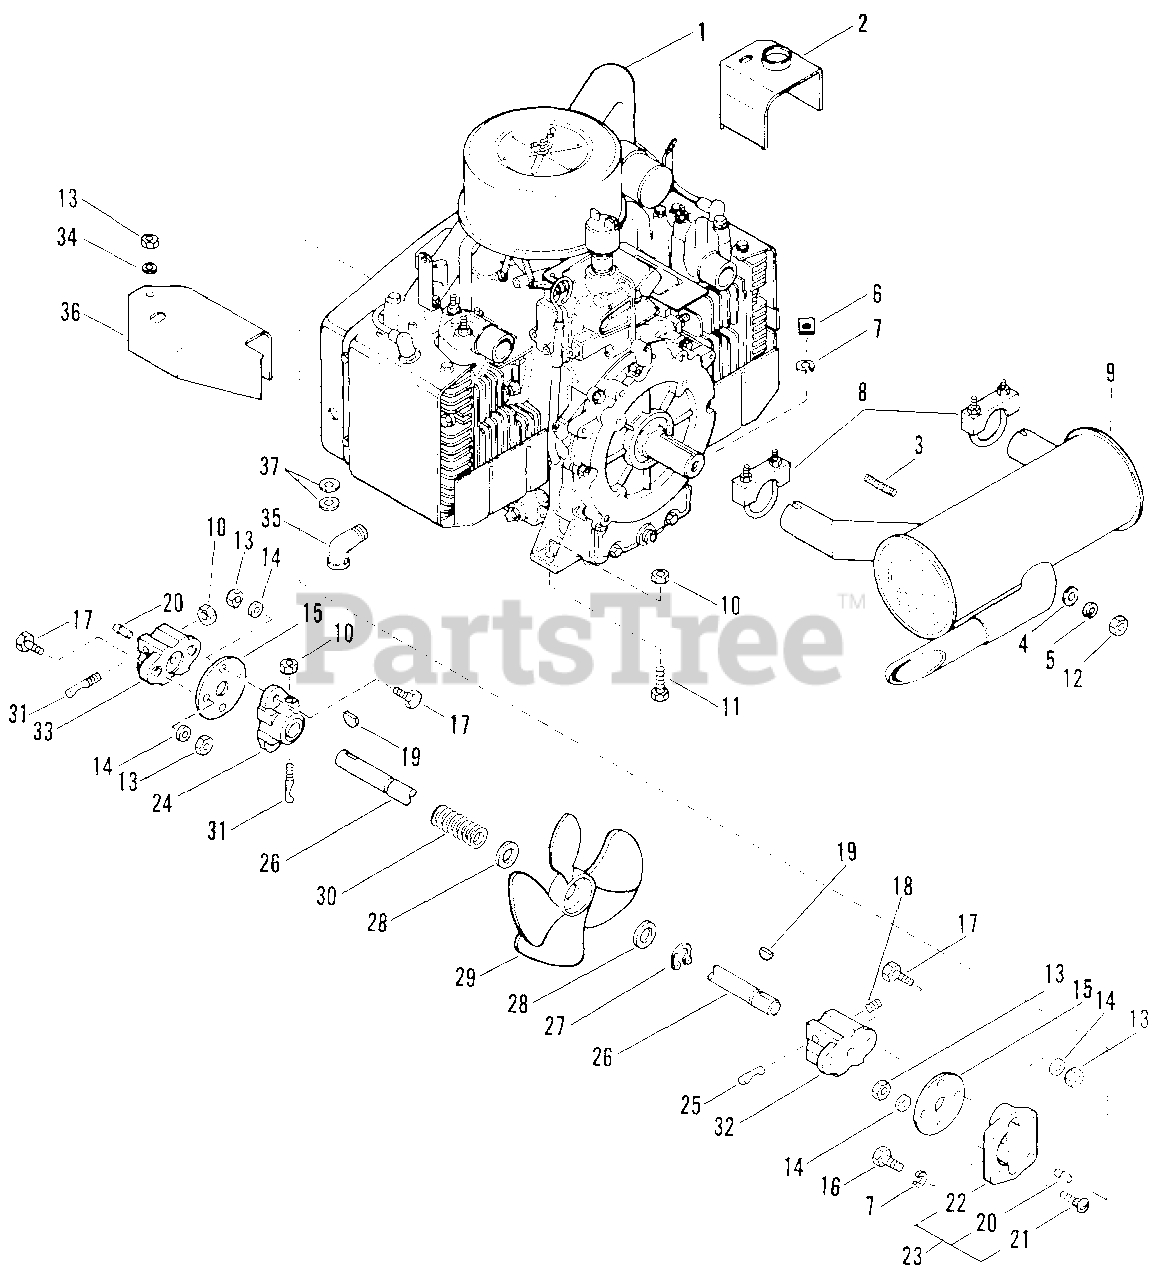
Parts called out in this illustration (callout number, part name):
1	Engine, 17 HP Kohler Twin K422
2	Left Exhaust Shield
3	Engine Stud
4	Washer, Flat .250 x .500 x .049
5	Washer, Lock 1/4 Reg.
6	Nut, Special 3/8-16
7	Washer, Lock 3/8 Reg.
8	Exhaust Clamp, 1.50
9	Muffler, Twin Exhaust
10	Nut, Lock 3/8-16
11	Bolt, Hex 3/8-16 x 1.25
12	Nut, Hex 1/4-20
13	Nut, Lock 5/16-18
14	Washer, Flat .375 x .734 x .065
15	Spacer Coupling
16	Bolt, Hex 3/8-16 x .875
17	Bolt, Hex 5/16-18 x .875
18	Set Screw, 3/8-16 x 1/2 SKHCUP
19	Key, Woodruff .187 x .75 #9
20	Pin, Groove 5/16 x 3/4 Type D
21	Bolt, Rib Neck 5/16-18 x 7/8
22	Drive Hub, Flywheel Twin
23	Engine Coupling Assembly, Twin
24	Drive Shaft Hub
25	Lock Stud
26	Drive Shaft
27	Ring, Retaining .750 Shaft
28	Washer, .752/.762 x 1.250 x .031
29	Fan
30	Spring, Comp. 2-1/2 Free Length
31	Lock Stud
32	Drive Hub, Twin Shaft
33	Drive Hub, Hydro
34	Washer, Flat .312 x .734 x .065
35	Street Elbow
36	Right Exhaust Shield
37	Washer, Flat .406 x .812 x .065
NS	Air Cleaner Decal
